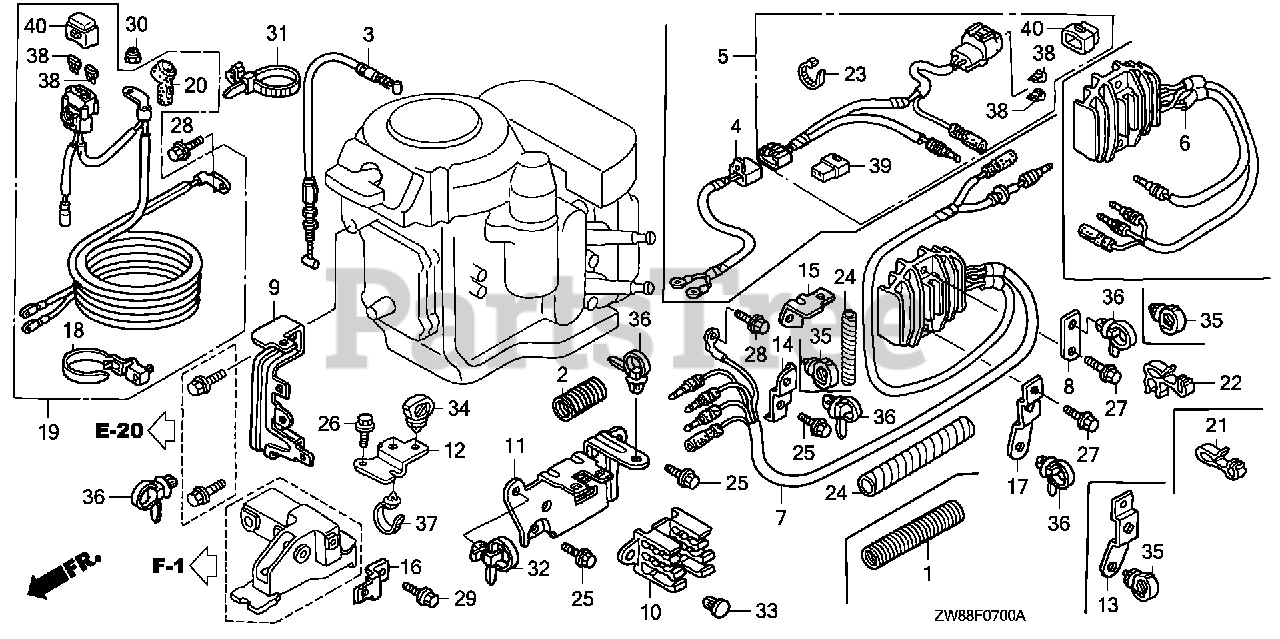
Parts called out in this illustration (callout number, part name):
3	CABLE, NEUTRAL STARTING
7	RECTIFIER ASSY., REGULATOR
8	BRACKET, CLIP F
9	BRACKET, CONNECTOR A
10	BRACKET, CONNECTOR (B)
11	BRACKET, CONNECTOR C
12	BRACKET, STARTER CABLE
14	BRACKET, CLIP B
15	BRACKET, FUSE CASE
17	BRACKET, E-CLIP
18	BAND, WIRE
19	CABLE ASSY., STARTER
20	COVER, MAGNETIC SWITCH TERMINAL
22	CLAMP, DISTRIBUTOR WIRE
24	TUBE, SPIRAL A
25	BOLT, FLANGE (6X14) (CT200)
26	BOLT, FLANGE (6X14) (CT200)
27	BOLT, FLANGE (6X26) (CT200)
28	BOLT, FLANGE (6X12)
30	NUT, LOCK (6MM)
31	BAND, WIRE (95MM)
32	STRAP, CABLE (118MM) (BLACK)
33	CLIP, ANCHOR
34	CLIP, HARNESS
36	CLIP, HARNESS BAND (151.5MM) (NATURAL)
37	BAND, WIRE HARNESS (123.5MM) (BLUE)
38	FUSE, BLADE (20A)
40	COVER ASSY., FUSE (20A)
